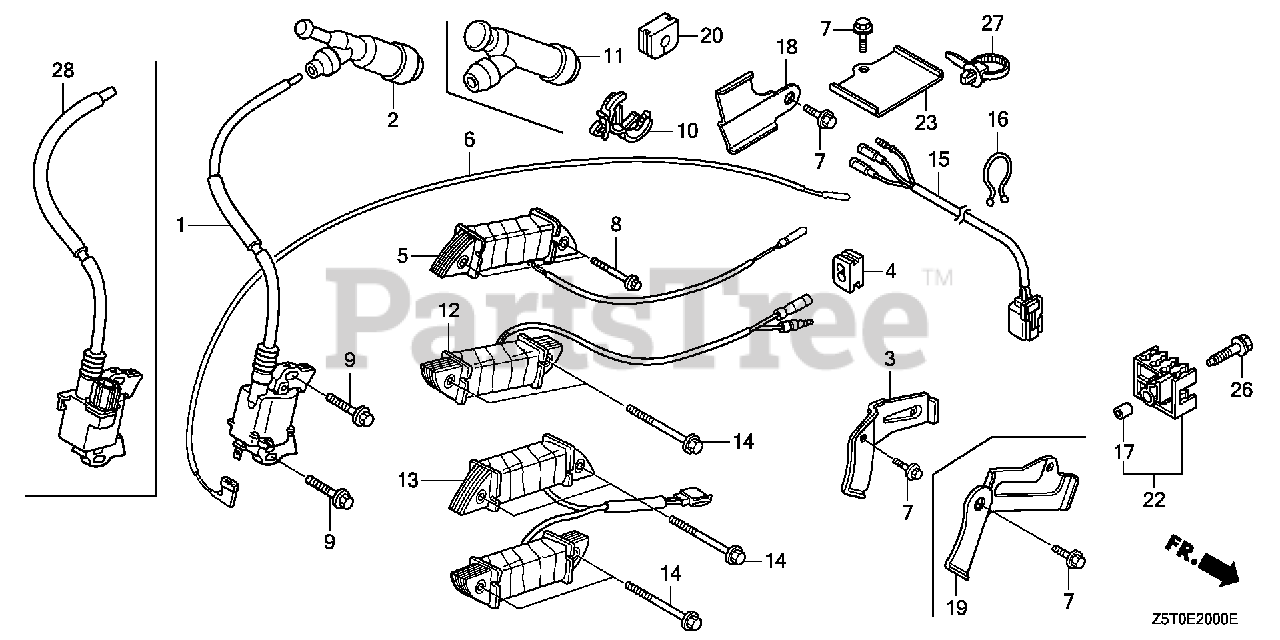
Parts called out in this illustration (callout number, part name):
2	CAP ASSY., NOISE SUPPRESSOR (NGK Y-EZD)
4	GROMMET, WIRE
9	BOLT, FLANGE (6X28) (CT200) Use up to Engine SN 1530314.
10	CLIP, WIRE HARNESS
15	WIRE HARNESS ASSY., ENGINE
28	COIL ASSY., IGNITION
